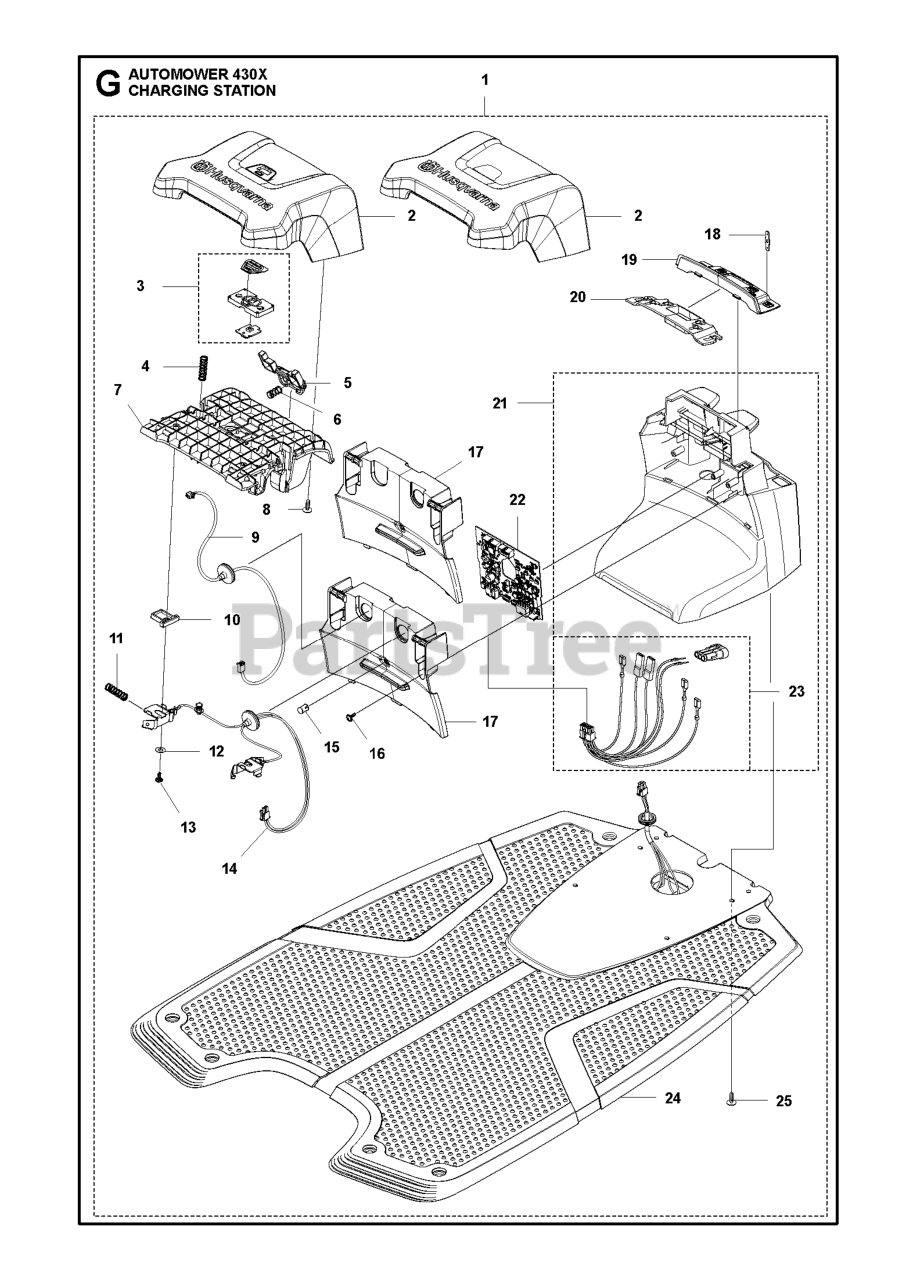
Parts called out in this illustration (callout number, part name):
1	Charging Station
2	CAP CHARGING STATION
2	CAP CHARGING STATION WITHOUT H
3	BUTTON KIT HOME
4	SPRING SPRING CAP
5	BUTTON CHARGING STATION, RELEA
6	SPRING STOP BUTTON
7	FRAME CHARGING STATION
8	SCREW 14MM
9	LOOM HOME BUTTON
10	DISTANCE CHARGING STATION
11	SPRING SPRING CAP
12	WASHER
13	SCREW 14MM
14	CABLE ASSY CHARGING CONTACTS
15	LENS DIODE
16	SCREW 14MM
17	LID CHARGING STATION 330, TWO
17	LID CHARGING STATION 320, ONE
18	TERMINAL TERMINAL CHARGING STA
19	PANEL CHARGING STATION 330, TW
20	HOLDER CHARGING STATION
21	HOUSING ASSY CHARGING STATION
22	PRINTED CIRCUIT ASSY PCBA CS B
23	CABLE KIT GENERATOR BOARD
24	BASE ASSY CHARGING STATION
25	SCREW 14MM
